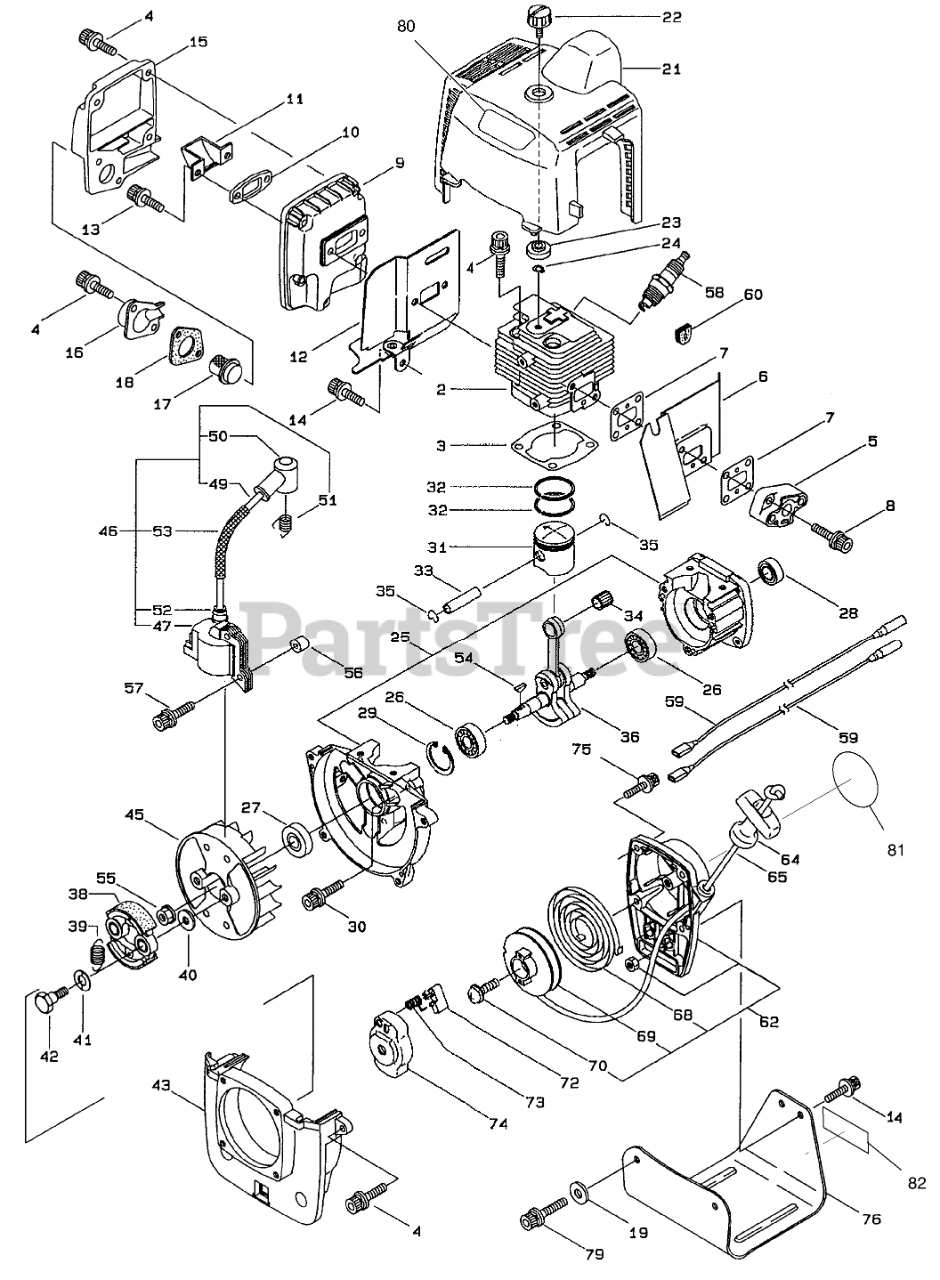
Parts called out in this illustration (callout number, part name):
2	CYLINDER
3	GASKET
5	INSULATOR
6	DUCT - AIR
7	GASKET
8	SCREW
9	BODY - MUFFLER
10	SHIELD
11	PLATE
12	GASKET - MUFFLER
13	CAPSCREW
15	COVER - MUFFLER
16	COVER - SPARK ARRESTER
17	ARRESTER - SPARK
18	GASKET - SPARK ARRESTER
19	WASHER
21	COVER - TOP
23	SPACER
25	CRANKCASE
26	BEARING
27	SEAL - OIL
28	SEAL - OIL
29	RING - SNAP
31	PISTON
32	RING - PISTON
33	PIN - PISTON
34	BEARING - NEEDLE
35	CIRCLIP
36	CRANKSHAFT
38	SHOE - CLUTCH
39	SPRING - CLUTCH
40	WASHER
41	WASHER - WAVE
42	BOLT - CLUTCH
43	COVER - FAN
45	ROTOR
46	Ignition Coil Assembly (Incl. Ref. #47-53)
49	CABLE - IGNITION
50	CAP - PLUG
51	CONNECTOR
54	KEY - WOODRUFF
55	WASHER & NUT
56	SPACER
58	SPARK PLUG
60	GROMMET
62	Recoil Assembly (Incl. Ref. #63-70)
64	GRIP - STARTER
65	ROPE - STARTER
68	SPRING - SPIRAL
70	SCREW
73	SPRING - RETURN
74	STARTER
76	STAND - ENGINE
80	DECAL - TORO
81	DECAL - TORO
82	REPLACEMNT SERIAL PLT
